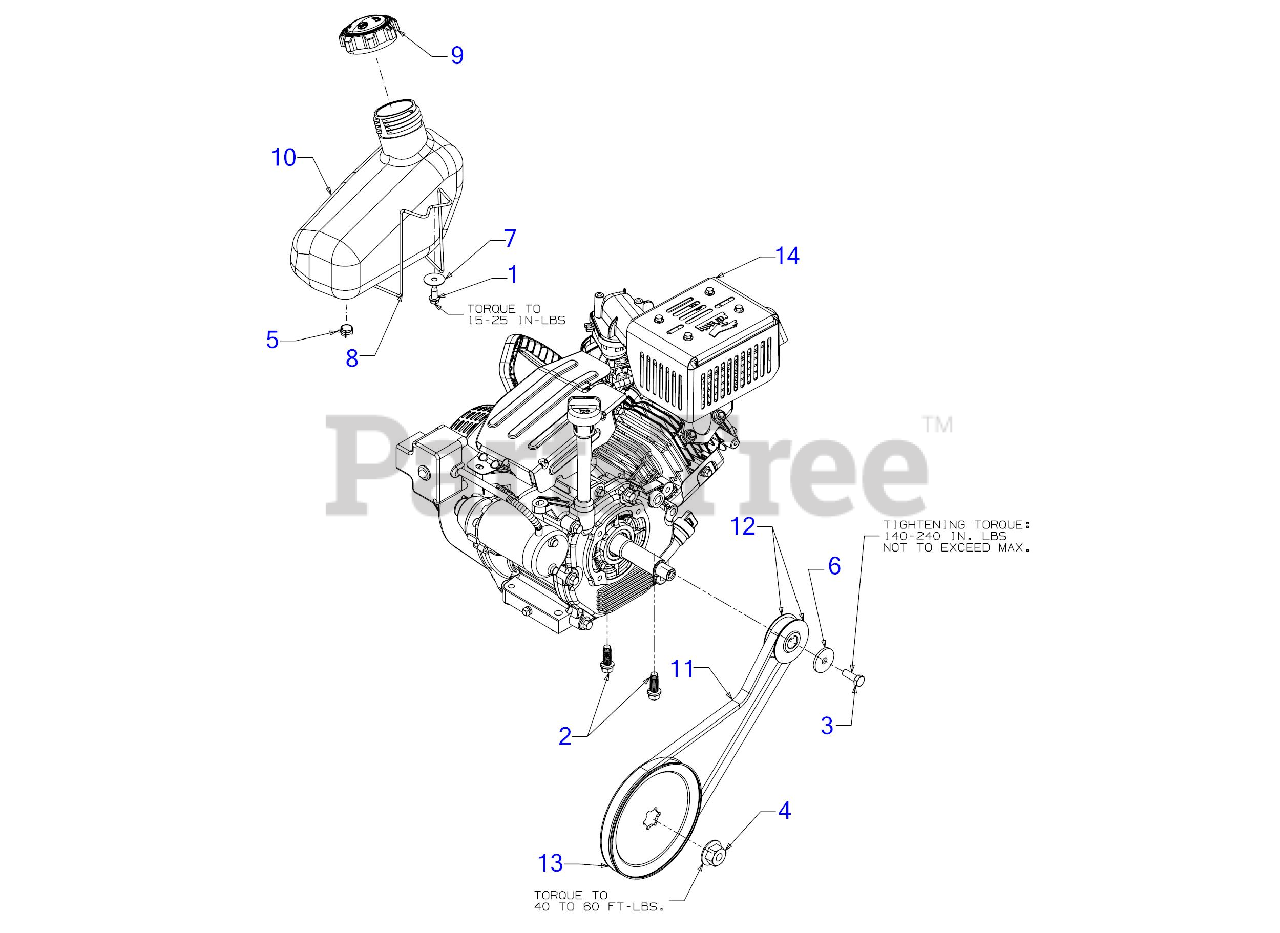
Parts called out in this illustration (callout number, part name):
1	SCREW 1/4-10:.625
2	SCREW 3/8-16 x 1
3	SCREW 5/16-24 x .875 GR5
4	FLANGE NUT W/HUB
5	HOSE CLAMP 1/20
6	WASHER-5/16 x 1.25X 1.27
7	FLAT WASHER
8	SUPPORT WIRE
9	FUEL CAP
10	FUEL TANK (2 QT)
11	V-BELT .500 x 35.
12	HALF PULLEY
13	AUGER PULLEY
14	COMPLETE ENGINE 208cc
